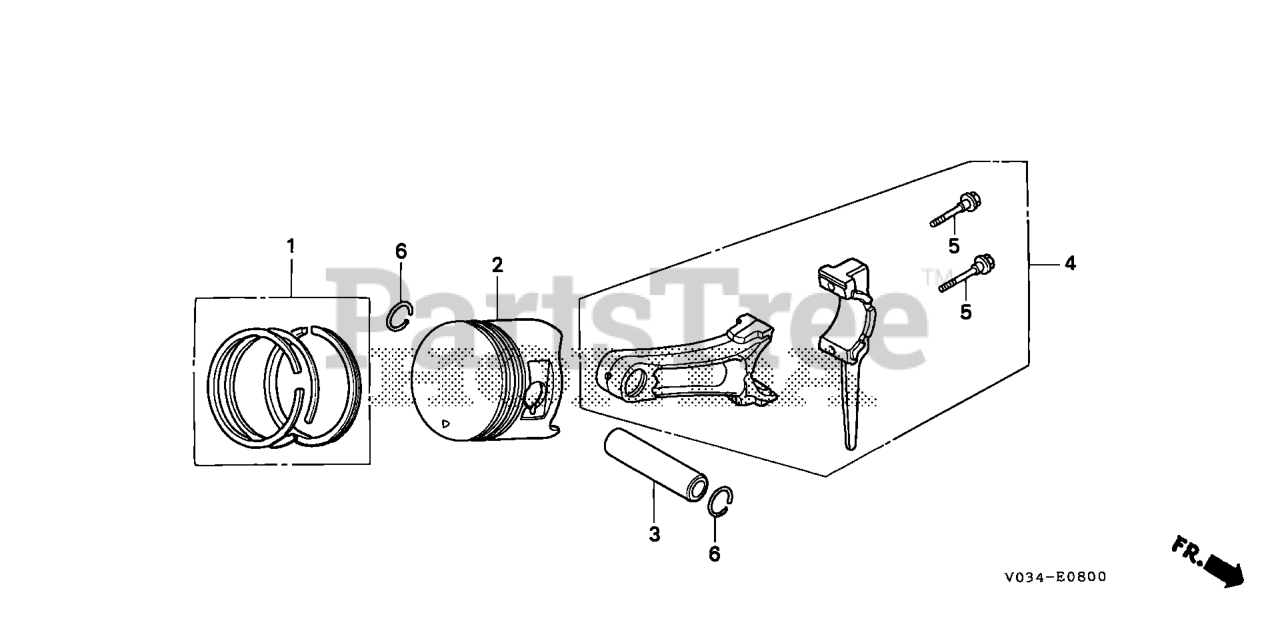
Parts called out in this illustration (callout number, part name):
1	RING SET, PISTON (STD)
1	RING SET, PISTON (OS 0.25)
1	RING SET, PISTON (OS 0.50)
1	RING SET, PISTON (0.75)
1	RING SET, PISTON (0.75) (TEIKOKU)
2	PISTON (STD)
2	PISTON (OS 0.25)
2	PISTON (OS 0.50)
2	PISTON (OS 0.75)
3	PIN, PISTON
4	ROD ASSY., CONNECTING (STD)
5	BOLT, CONNECTING ROD
6	CLIP, PISTON PIN (20MM)
